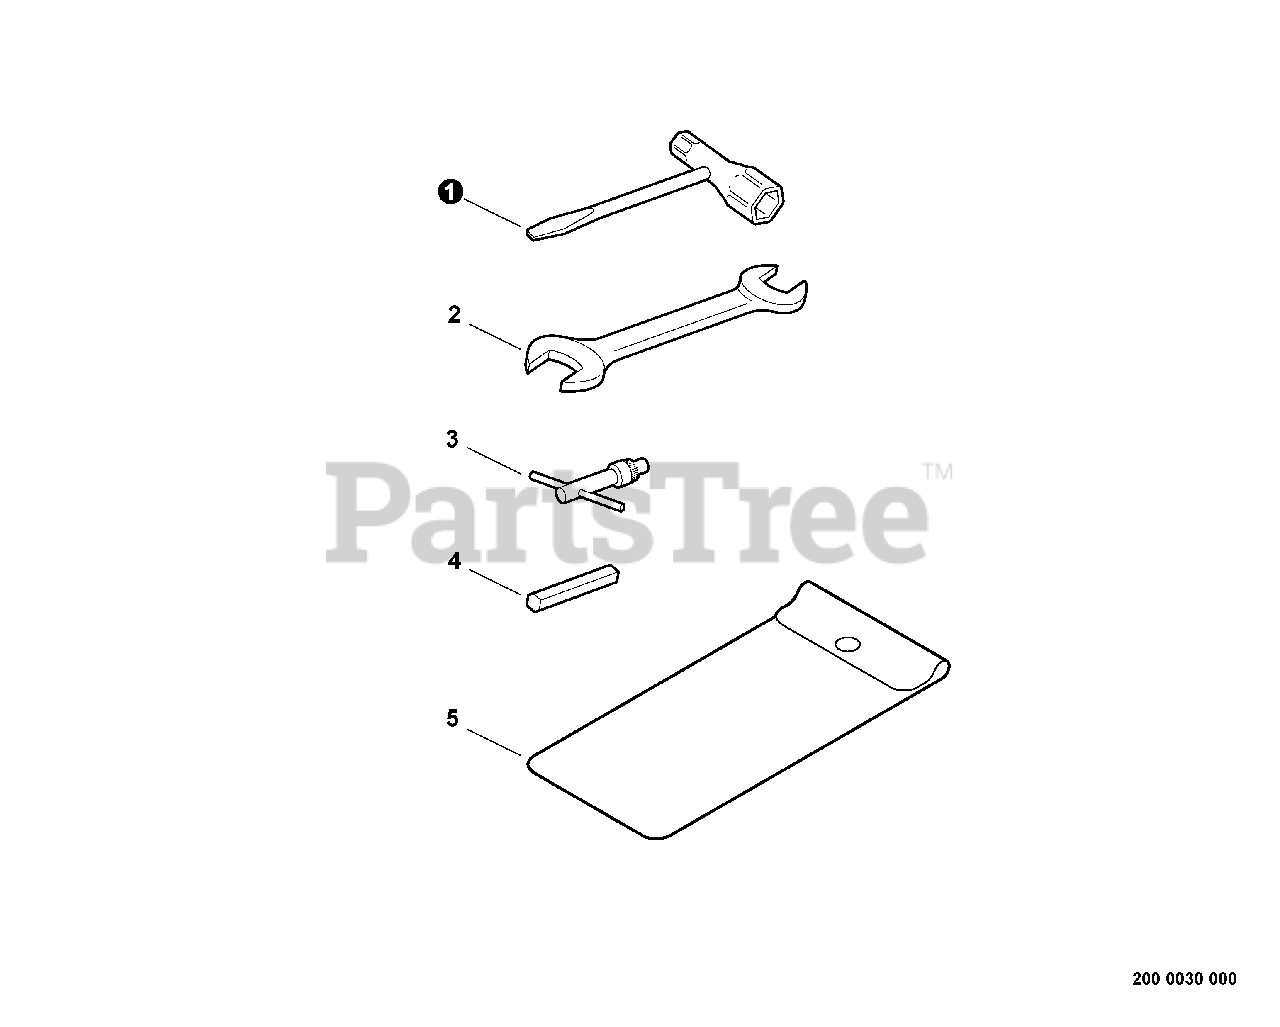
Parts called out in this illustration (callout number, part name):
1	T-WRENCH - 10X19mm
2	SPANNER - 17X19mm
3	KEY, CHUCK
5	BAG, TOOL
